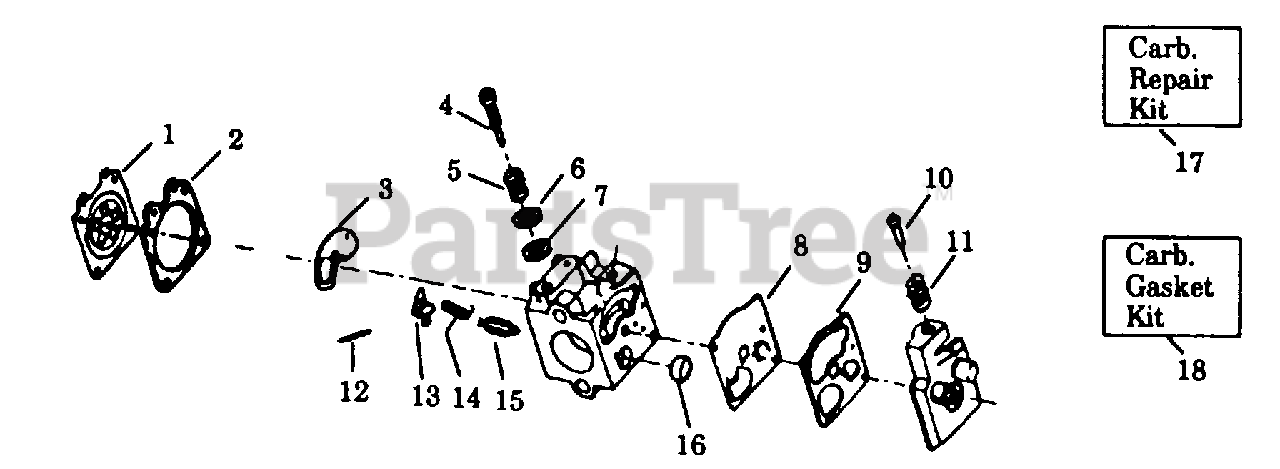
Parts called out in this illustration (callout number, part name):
1	Metering Diaphragm
2	Metering Diaphragm Gasket
3	Circuit Plate Gasket
4	Mixture Needle
5	Mixture Needle Spring
6	Mixture Needle Washer
7	"O" Ring Mixture
8	Fuel Pump Diaphragm
9	Fuel Pump Gasket
10	Idle Speed Screw
11	Idle Speed Spring
12	Metering Lever Pin
13	Metering Lever
14	Metering Lever Spring
15	Inlet Needle Valve
16	Fuel Inlet Screen
17	Carb. Kwik Repair Kit
18	Carb. Gasket/Diaphragm Kit
